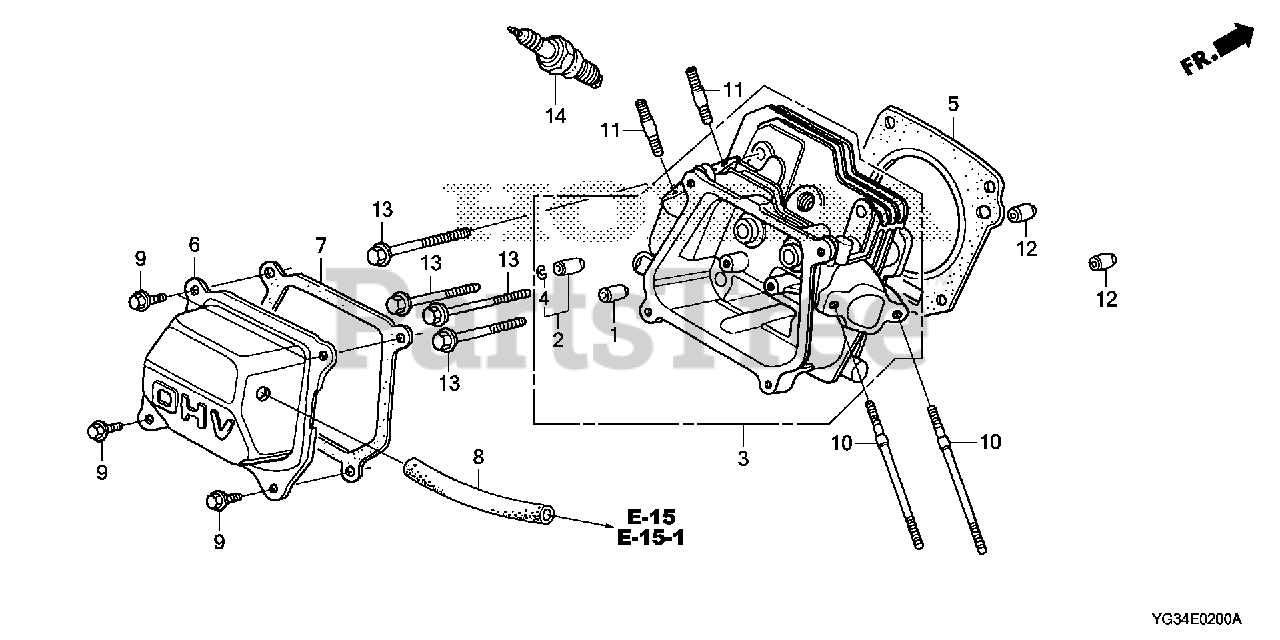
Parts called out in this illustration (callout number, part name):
1	GUIDE, VALVE (OVER SIZE) Use from Engine SN 6324986.
2	GUIDE, EX. VALVE (OS)
3	CYLINDER HEAD
4	CLIP, VALVE GUIDE Use from Engine SN 1231803.
5	GASKET, CYLINDER HEAD (NIPPON LEAKLESS)
6	COVER, HEAD
7	GASKET, CYLINDER HEAD COVER
7	GASKET, HEAD COVER
8	TUBE, BREATHER
9	BOLT, FLANGE (6X12) (CT200)
10	BOLT, STUD (6X109)
11	BOLT, STUD (8X32)
12	PIN A, DOWEL (10X16)
13	BOLT, FLANGE (8X60)
14	SPARK PLUG (BPR6ES) (NGK)
